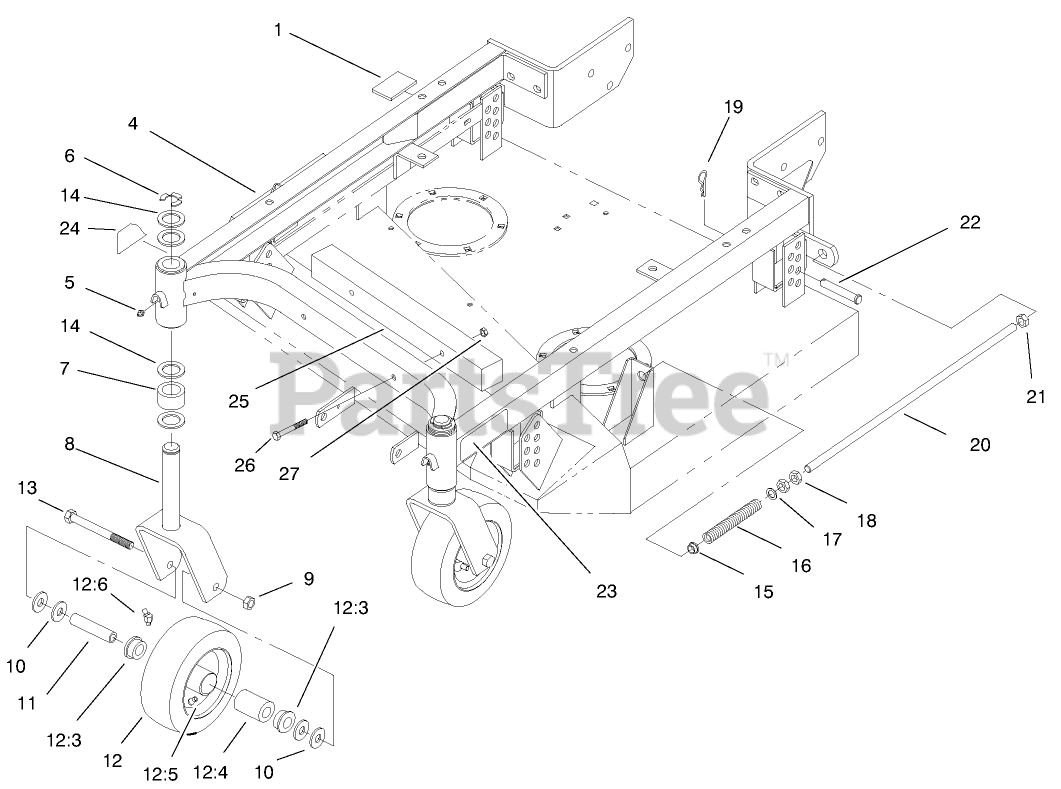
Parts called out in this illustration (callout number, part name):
1	CUSHION-RUBBER
4	CARRIER FRAME
5	FITTING-GREASE
6	RING-RETAINING
7	SPACER-CASTOR
8	Castor Fork
9	NUT-HEX
10	WASHER-FLAT
11	SPANNER-TIRE
12	CASTOR WHEEL ASM
12:3	BEARING-OUTSIDE
12:4	BEARING-ROLLER
12:5	STEM-VALVE
12:6	FITTING-LUBE, 45 DEG
13	SCREW-HH
14	WASHER-THRUST
15	BUSHING-FLANGE
16	SPRING
17	WASHER
18	NUT-JAM
19	PIN-HAIR
20	SHAFT-ADJUSTING
21	NUT-LOCK, NI
22	PIN-CLEVIS
23	DECAL-HOC, LH
24	DECAL-HOC, RH
25	Weight
26	SCREW-HH
27	NUT-LOCK, NI
